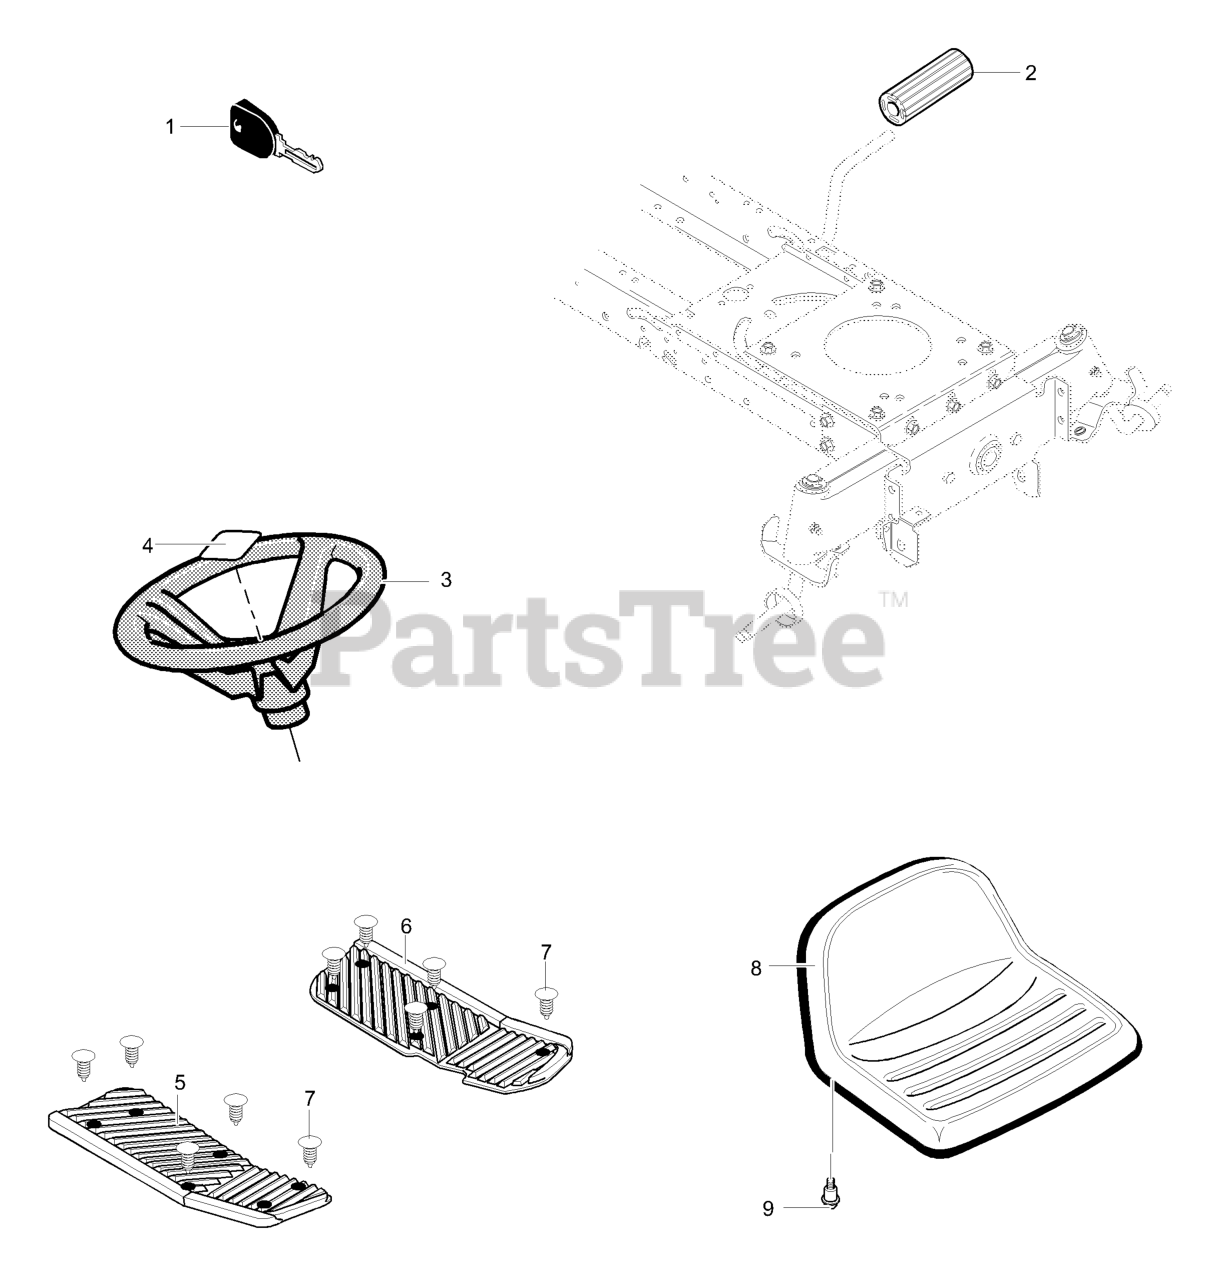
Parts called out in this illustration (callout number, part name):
1	Ignition Key
2	Cover, Pedal Brake/Clutch
3	Steering Wheel
4	Insert, 4-Spoke
5	Foot Pad RH
6	Foot Pad LH
7	Ratchet Fastener
9	Shoulder Bolt 5/16-18
